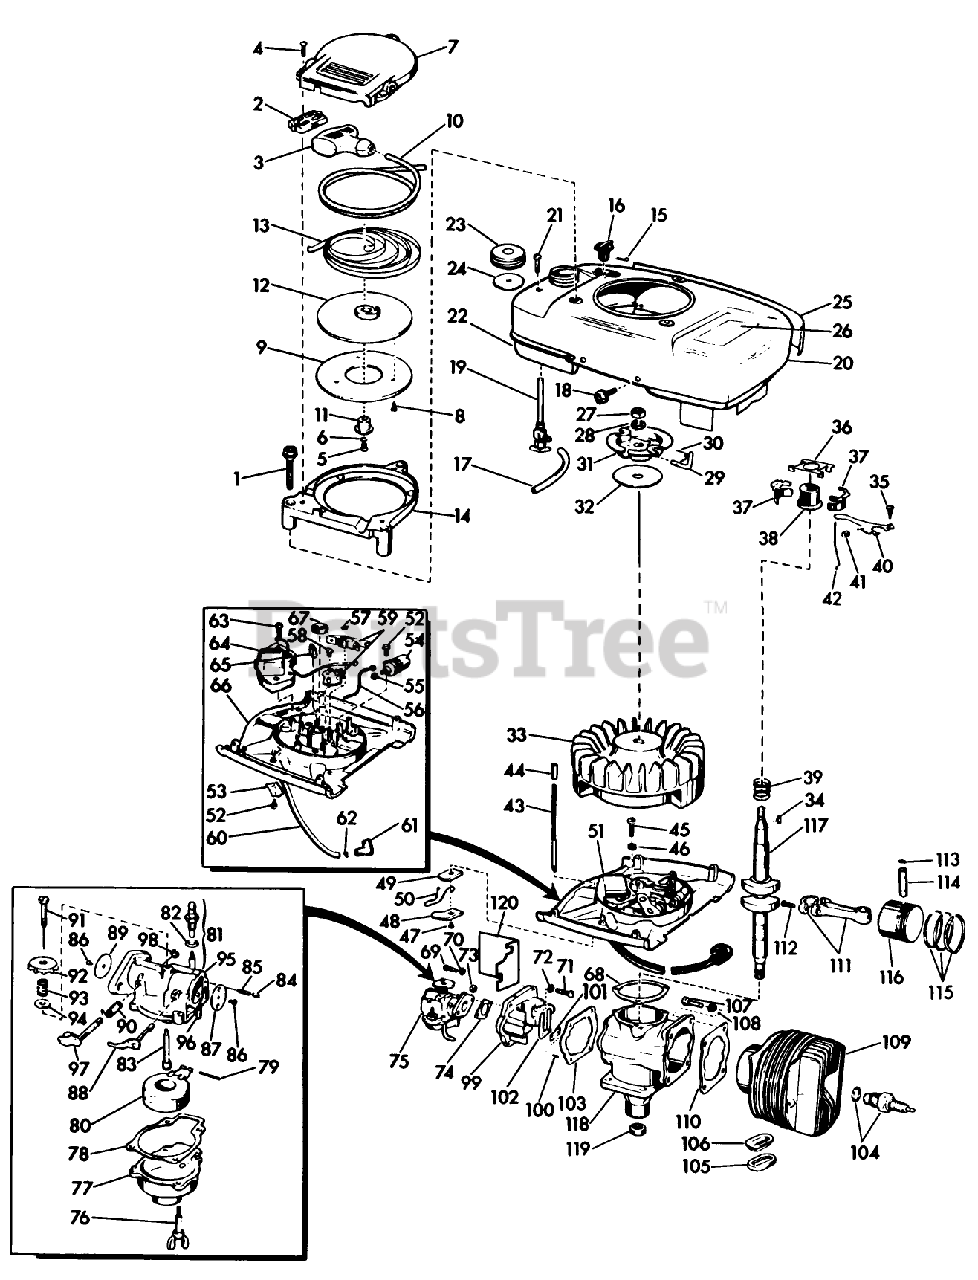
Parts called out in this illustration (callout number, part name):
13	RECOIL SPRING
14	Base-Starter
15	Cotter Pin-Choke Knob
16	KNOB, CHOKE BAR
18	SCREW S
19	VALVE&SCREEN SM
23	Gas Cap
29	PIN - STARTER
38	COLLAR S
40	GOVERNER LEVER AY
41	WEAR BLOCK S
42	GOVERNOR ROD S
47	Screw Shut-off Switch
59	BREAKER AY. S
61	Cover-Rubber
65	Oiler Wick
68	GASKET S
69	SCREW S
73	STOP NUT
74	GASKET S
86	Screw-Choke Disc
87	Disc-Choke
88	CHOKE SHAFT&LVR AY
90	SPRING
91	NEEDLE AY. S
93	Spring-Ndl. Adj.
101	PLATE-BACKUP, REED
104	Spark Plug
112	Screw-Connecting Rod
117	Crankshaft
118	Crankcase Oil Seal and Bearing Assembly
